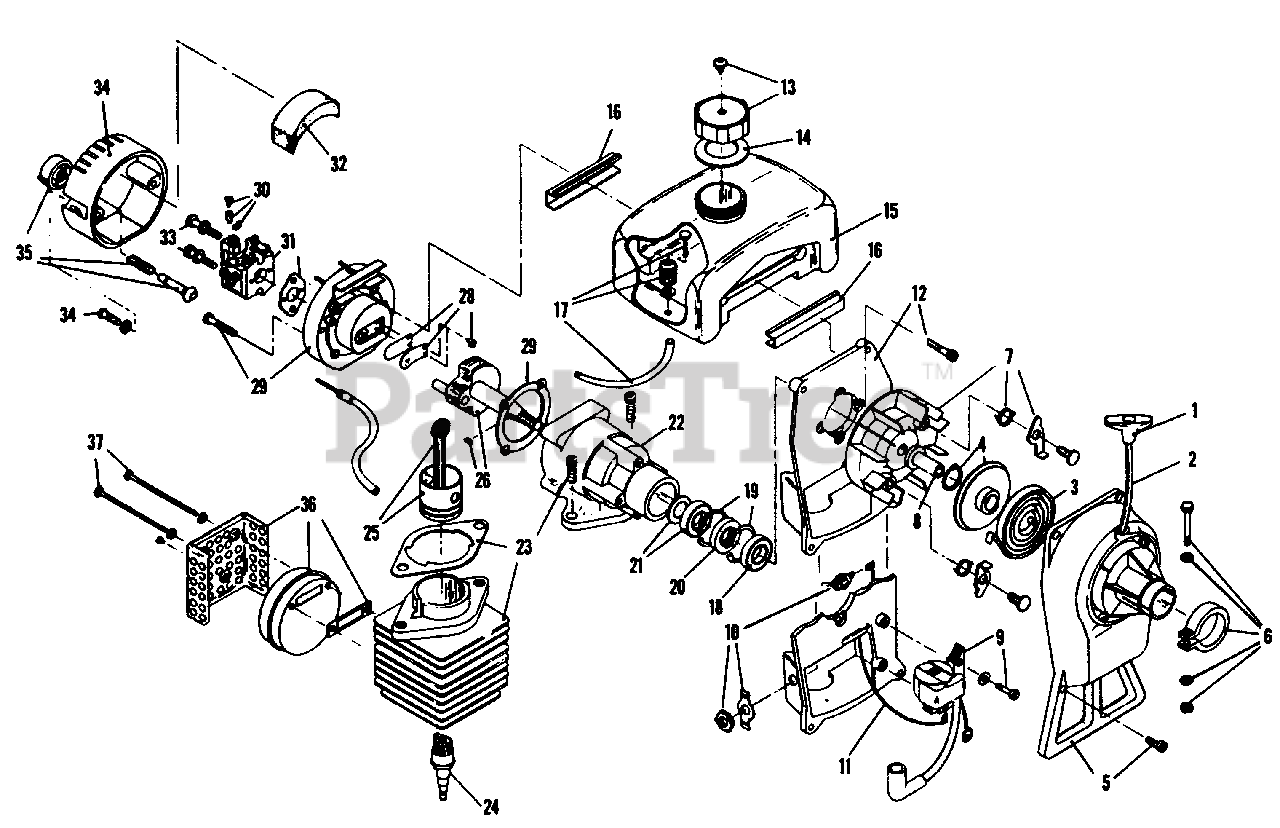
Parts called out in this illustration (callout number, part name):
1	Pull Handle
3	Recoil Spring
4	Recoil Pulley Assembly
5	Starter Housing Assembly
6	Upper Clamp Assembly
7	Flywheel Assembly
8	Square Drive Nut
9	Module Assembly
10	Switch Assembly
11	Wire Lead
12	Shroud Assembly
13	Fuel Cap Assembly
14	Fuel Cap Gasket
15	Fuel Tank
16	Tank Mounting Pads
17	Fuel Line Assembly
18	Outer Bearing
19	Snap Ring Assembly
21	Inner Bearing Assembly
22	Crankcase
23	Cylinder Assembly
24	Spark Plug DJ-8J
25	Piston and Rod Assembly
26	Power Shaft Assembly
28	Reed Assembly
29	Carburetor Mount Assembly
30	Throttle Adjustment Assembly
31	Carburetor Assembly
32	Air Cleaner
33	Carburetor Mount Screw Assy.
34	Air Cleaner Cover Assembly
35	Choke Knob Assembly
36	Muffler Assembly
37	Muffler bolt Assembly
